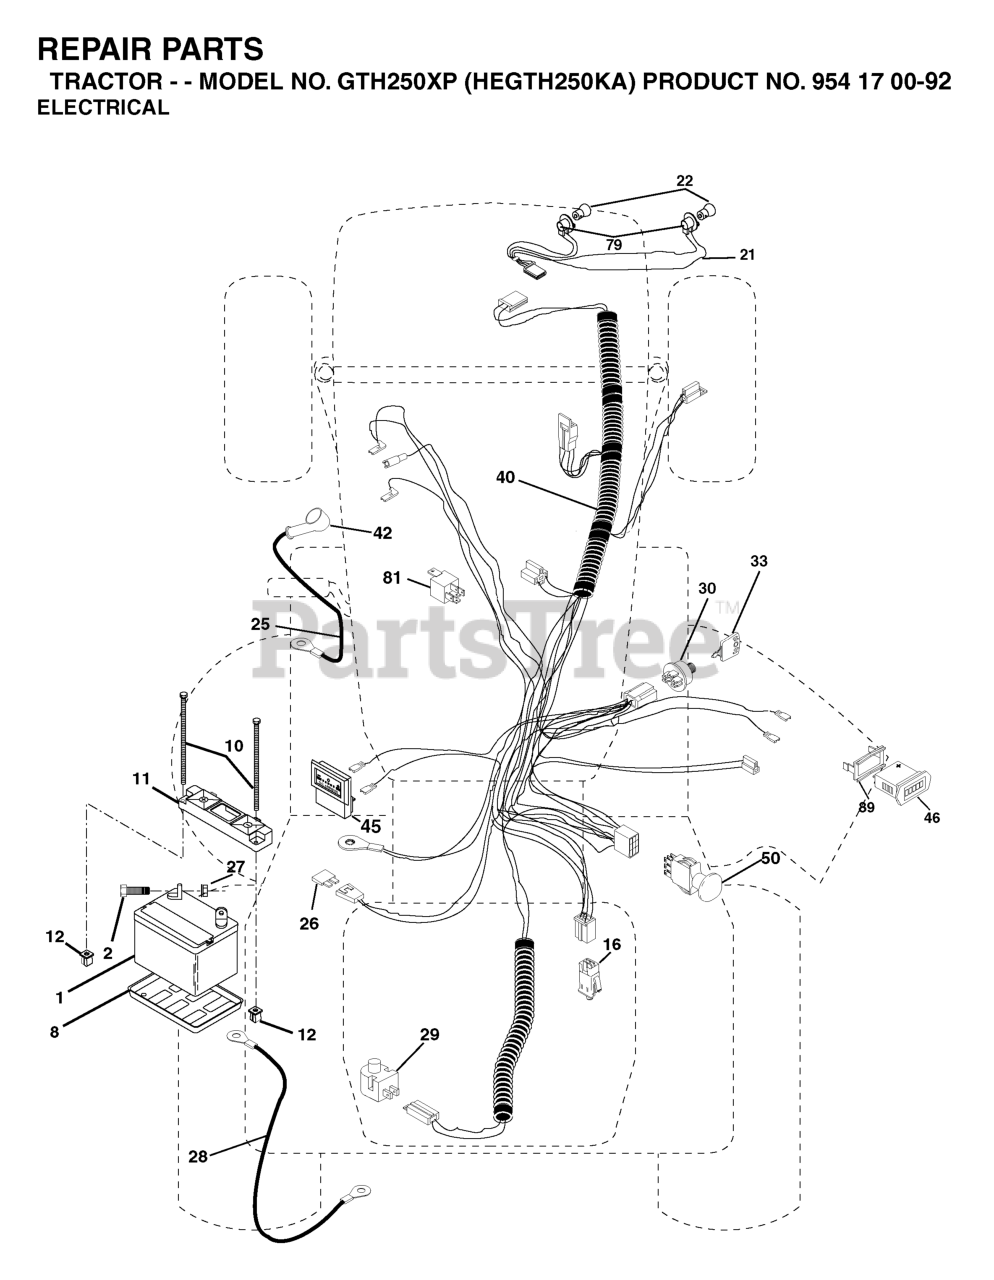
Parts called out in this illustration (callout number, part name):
1	BATTERY 12V .35 AMP
2	BOLT.HEX.1/4.X.3/4.DICHROMATE
8	BATTERY TRAY T
10	BOLT 1/4-20 X 7.5
11	BATTERY HOLDDOWN FRONT MOUNT
12	NUT, PUSH NYLON 1/4" BATTERY
16	SWITCH INTERLOOK PUSH-IN
21	HARNESS.W/LIGHT SOCKET
25	CABLE.4GA.RED.W/16GA.RED.WIRE
27	NUT
28	CABLE, GROUND
29	PLUNGER SWITCH (COLOR:OLIVE)
30	IGNITION SWITCH
33	KEY MLD GEN DELTA
40	HARNESS, IGNITION
42	COVER.TERMINAL.RED
46	HOUR METER
50	RP.PTO.SWITCH.8 TERMINAL.BLACK
79	BULB HOLDER ASM.
81	RELAY.ASSY.T
89	BRACKET SNAP-IN HOURMETER
